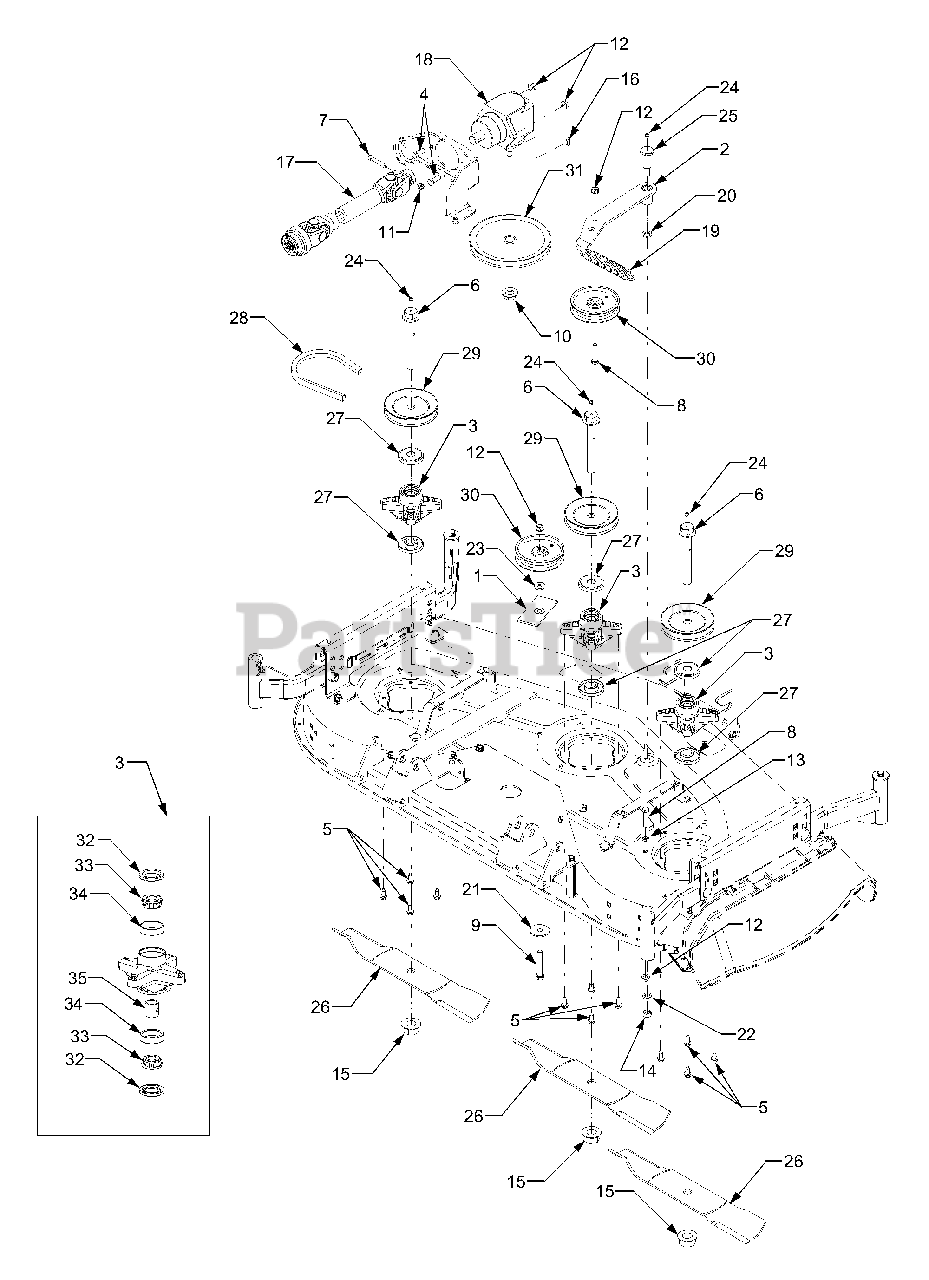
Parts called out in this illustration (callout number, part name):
1	Assembly, Spacer
2	Bracket, Idler
3	Assembly, Spindle
4	Screw, Hex Cap 3/8-16 x 1.0 GR5
5	Screw, Hex Wash Hd Tapp 5/16-18 x .75
6	Bolt, Spindle, 3/4-16 x 4.25
7	Screw, Sock. Hd. 5/16-18 x 1.75
8	Screw, Hex Cap 3/8-16 x 1.75 GR5
9	Screw, Hex Cap 3/8-16 x 2.25 GR5
10	Nut , Hex Flanged 5/8-18
11	Nut, Hex Nylon Lock 5/16 -18
12	Nut, Flange Lock 3/8-16
13	Nut, Hex Jam, 3/8-16 GR5
14	Nut, Hex 7/16-14
15	Nut, Hex Flange, 3/4-16
16	Key, Hi-Pro
17	Shaft, Drive
18	Drive, Right Angle
19	Spring, Extension 6.14" Lg.
20	Washer, Flat, .45 x 1.25 x .164
21	Washer, Flat .406" I.D.
22	Washer, Lock 7/16" I.D.
23	Washer, Flat .47 x .75 x .06
24	Fitting, Lube
25	Bolt, Shoulder .68" Dia. x 1.59
26	Blade, High Lift 18.5" Lg.
27	Spacer, Deck Spindle
28	Belt, "V" 120" Lg.
29	Pulley, "V"
30	Pulley, Flat Idler
31	Pulley, Drive
32	Seal, Oil
33	Bearing, Cone
34	Cup, Bearing
35	Spacer, Bearing
